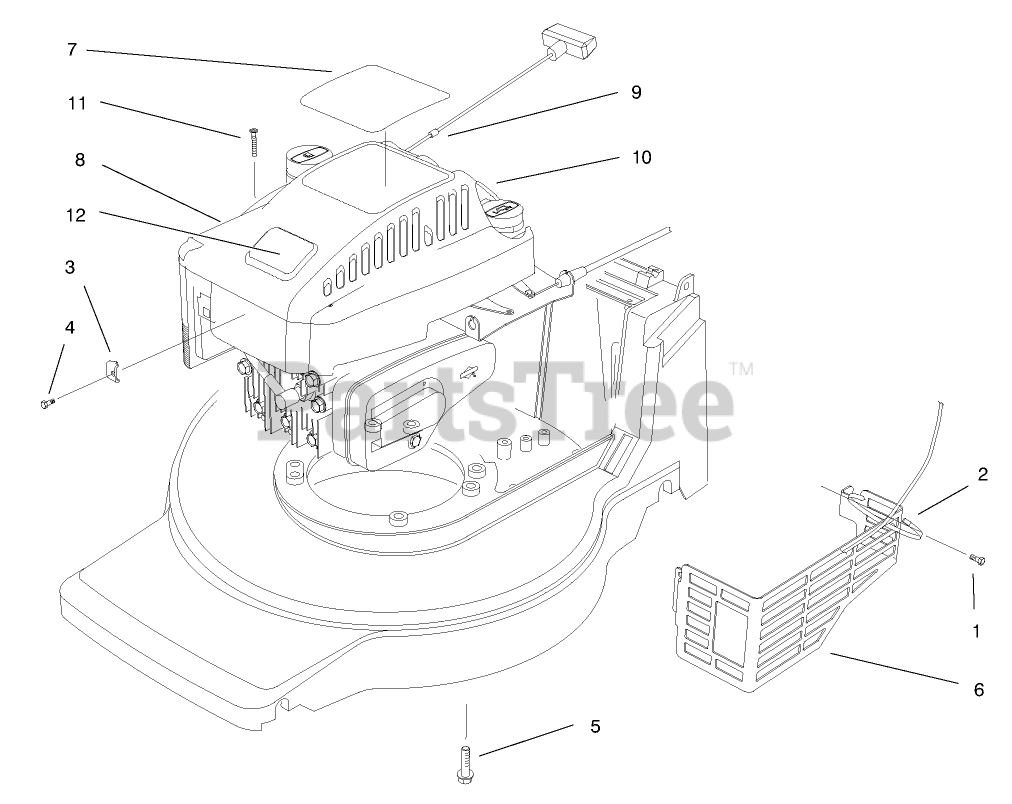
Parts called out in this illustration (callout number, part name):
1	SCREW-HWH
2	TIE-CABLE
3	CLAMP-CASING
4	SCREW-CLAMP
5	SCREW-HWH
6	SHIELD-MUFFLER
7	DECAL - RECOIL
9	STOP-ROPE
10	SHROUD-ENGINE
11	SCREW-PPH
12	PLATE-LOGO
